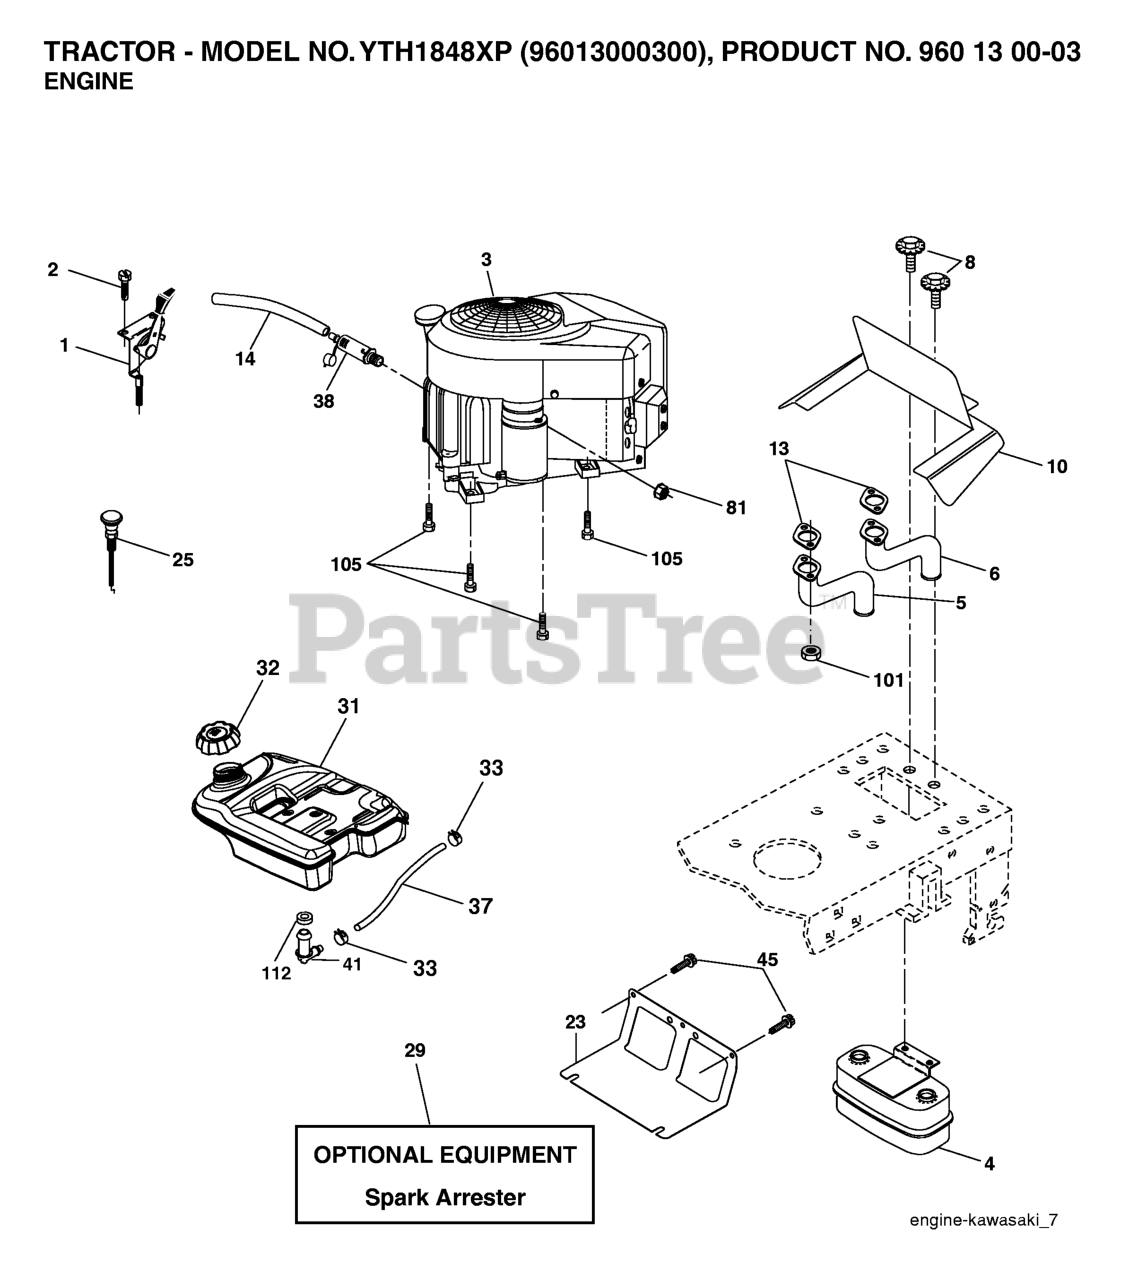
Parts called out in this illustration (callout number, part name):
1	CONTROL, THROTTLE
2	SCREW
4	MUFFLER.TWIN.CYL.LOW.TONE
5	EXHAUST.TUBE.LH.KAWASAKI.
6	EXHAUST.TUBE.RH.KAWASAKI.
8	BOLT.5/16-18UNCX3/4 W/SEMS.BLK
10	RP SHIELD HEAT MUFFLER
14	TUBE, DRAIN OIL ASM.
23	SHIELD.BROWNING.DBR.GUARD
25	CONTROL THROTTLE
29	KIT.SPARK ARRESTOR 794945 B&S
31	4.0 REAR FUEL TANK
32	TANK CAP
33	HOSE CLAMP
37	REPL BY 532 00 85-43
41	STEM FUEL TANK
45	SCREW, 3/8-16X3/4
81	NUT
101	NUT.HEX.FLANGE.TOPLOCK
105	SCREW 3/8-16X1
112	BUSHING OUTLET T
